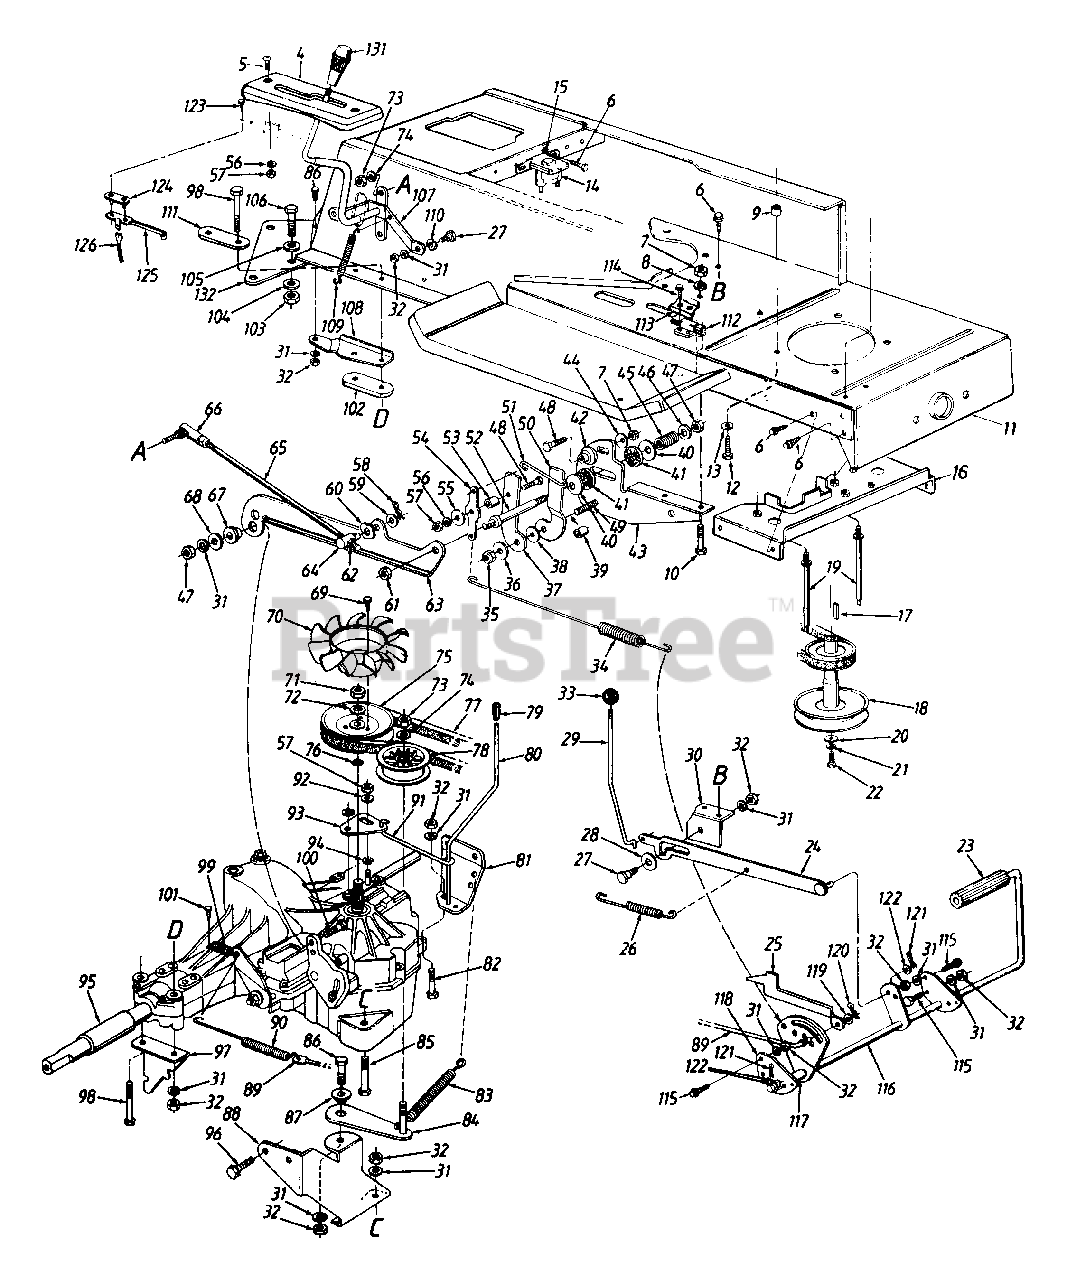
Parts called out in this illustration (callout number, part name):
4	Index Bracket
5	Pan Hd. Mach. Scr. 1/4-20 x .75" Lg.
6	Hex Wash. Hd. TT-Tap Scr. 1/4-20 x .5" Lg.
7	Hex Nut 1/4-28 Thd.
8	L-Wash. 1/4" I.D.
9	Shld. Spacer .38" I.D.
10	Hex . Bolt 1/4-28 x .62" Lg.
11	Lower Frame Ass'y.
12	Hex Tap Scr. 3/8-16 x 1.5" Lg.
13	Fl-Wash. .406" I.D. x 1.25"
14	Solenoid
15	Ext. L-Wash. 1/4" I.D.
16	Belt Guard Brkt. Ass'y.
17	Sq. Key 1/4" x 2" Lg.
18	Engine Pulley
19	Belt Guard Stud 3.6" Lg.
20	Fl-Wash. 7/16" I.D. x 1.25" O.D.
21	L-Wash. 7/16" I.D.
22	Hex Bolt 7/16-20 x 1.5" Lg.
23	Foot Pad
26	Foot Pedal Return Spring
27	Shld. Bolt .437" Dia. x .268"
28	Fl-Wash. 7/16" I.D. x 1-3/8" O.D.
31	L-Wash. 5/16" I.D.
32	Hex Nut 5/16-18 Thd.
34	Neutral Return Spring
35	Hex Nut 5/16-24 Thd.
36	Fl-Wash. .344" I.D. x 1" O.D.
37	Scissor-Flat
38	Fl-Wash. .33" I.D. x 1.25" O.D.
40	Bell-Wash. .4" I.D. x 1.13" O.D.
41	Friction Washer
42	Centering Gauge Spacer
43	Neutral Return Mtg. Brkt.
44	Bell-Wash. .265" I.D. x .75" O.D.
45	Comp. Spring 1.19" Lg.
46	Fl-Wash. .312" I.D. x .75" O.D.
47	Hex Nut 5/16-24 Thd.
48	Hex Bolt 1/4-28 x 1" Lg. (Gr. 5)
49	Rib Neck Bolt 5/16-24 x .84" Lg.
50	Scissor-Offset
51	Neutral Return Rod
52	Friction Disc Stud
53	Shld. Spacer
54	Neutral Return Lever
55	Fl-Wash. .265" I.D. x 1" O.D.
56	L-Wash. 1/4" I.D.
57	Hex Nut 1/4-20 Thd.
58	Hairpin Clip
59	Ft-Wash. .375" I.D. x .87" O.D.
60	Spring Wash. .39" I.D.
61	Hex L-Nut 3/8-24 Thd.
62	Hex Jam Nut 3/8-24 Thd.
63	Neutral Return Brkt.
64	Ferrule 3/8-24 Thd.
65	Control Rod
66	Ball Joint 3/8-24 Thd.
67	Shld. Spacer .5" Dia. x .27" Lg.
68	Fl-Wash. .349" I.D. x .879" O.D.
69	Hex Wash. Hd. Tap Scr. #12 x 3/8" Lg.
70	Fan
71	Hex Not 1/2-20 Thd.
72	L-Wash. 1/2" I.D.
73	Hex Nut 3/8-24 Thd.
74	L-Wash. 3/8" I.D.
75	Transmission Pulley
76	Wire Ring
77	"V"-Belt
78	Fl-Idler Pulley 2.75" O.D.
79	Rod End Grip
80	Bypass Control Lever
83	Ext. Spring 6.12
86	Hex Bolt 5/16-18 x .75" Lg.
87	Shld. Spacer .5" Dia. x .27" Lg.
88	Transaxle Support Brkt. - R.H.
89	Brake Rod 24.94" Lg.
90	Ext. Spring
91	Bypass Actuator Rod
92	Fl-Wash. .281" I.D. x .5" O.D.
93	Bypass Adjustment Brkt.
94	External L-Wash. 1/4" I.D.
95	Sleeve .758" I.D. x 1" O.D.
96	Hex . Wash. TT-Tap Scr. 5/16-18 x .62" Lg.
99	Tension Spring
100	Hex Bolt 5/16-24 x 1" Lg. (Special)
101	Hex Wash. Hd. AB-Tap Scr. #10 x .5" Lg.
102	Transaxle Spacer
103	Hex Nut 7/16-14 Thd. (Gr. 5)
104	Fl-Wash. .469" I.D. x .875" O.D.
105	Bell-Wash. .46" I.D. x 1.13" O.D.
106	Hex Bolt 7/16-14 x 1" Lg.
107	Speed Control Lever Ass'y.
110	Spr-Wash. .445" I.D. x .75" O.D.
112	Safety Switch (Clutch)
113	Switch Plate
114	Truss Mach. B-Tap Scr. #10 x .5" Lg.
115	Hex Wash. TT-Tap Scr. 5/16-18 x .75" Lg.
120	Cotter Pin 3/32" Dia.
121	Cotter Pin 1/8" Dia.
122	Fl-Wash. .64" I.D. x .94" O.D.
123	Hex Wash. Hd. AB-Tap Scr. #8 x .5" Lg.
124	Insulator Nut Plate
125	Reverse Safety Switch
126	Extension Wire
132	Hitch Plate Extension
